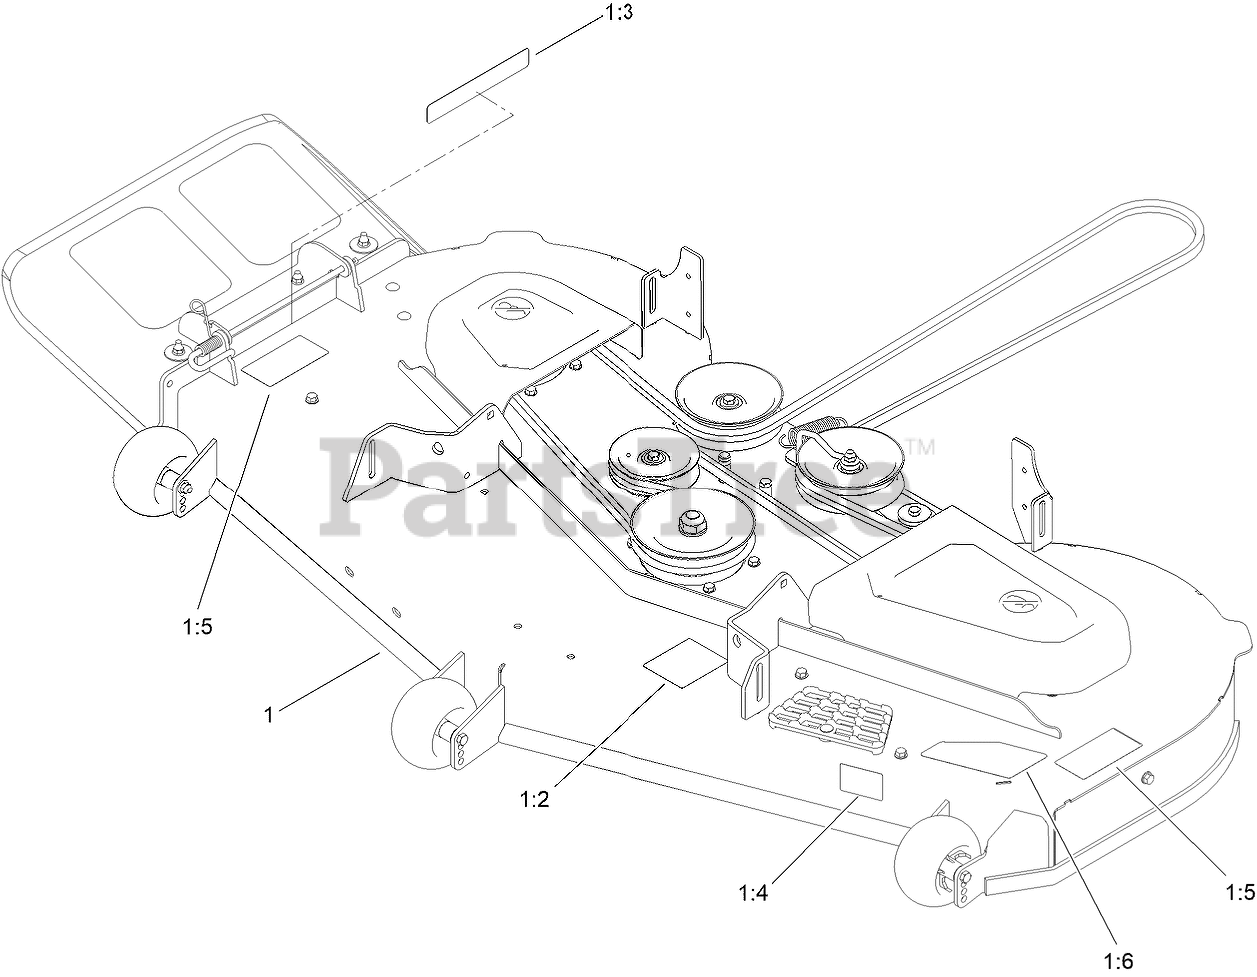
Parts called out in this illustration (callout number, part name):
1:2	DECAL-ROUTING, BELT
1:3	DECAL-DANGER
1:4	DECAL-SCALP, ANTI
1:5	DECAL-DANGER, DECK
1:6	DECAL-DECK
